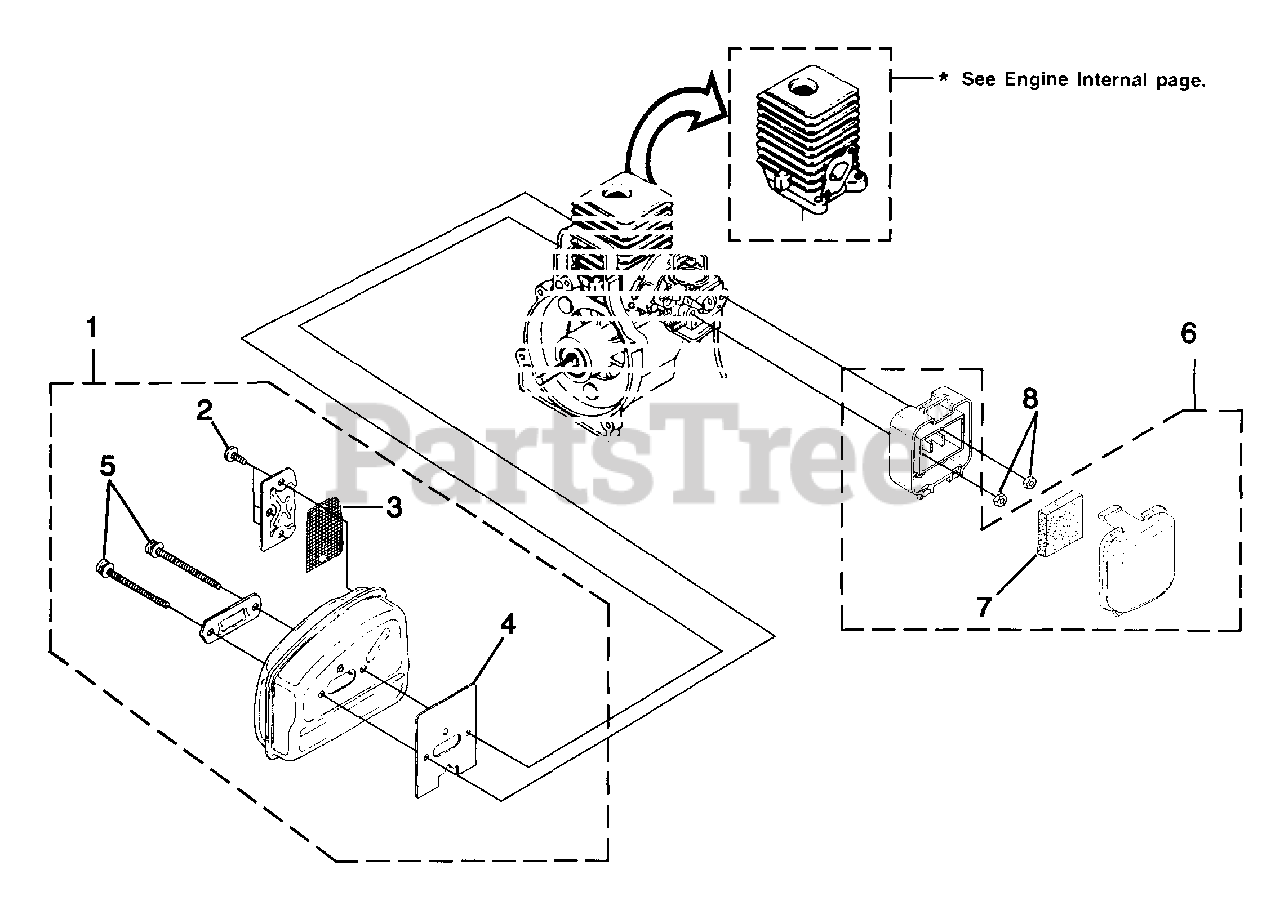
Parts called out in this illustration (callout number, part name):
1	MUFFLER ASSEMBLY
2	SCREW, Taptite - (8-32 X 3/8")
3	SCREEN-Spark
4	GASKET-Muffler
5	SCREW, Truss Hd. - (10-24 X 2.188)
6	Air Filter Kit
7	Filter-Air
8	NUT-Hex (10-24)
